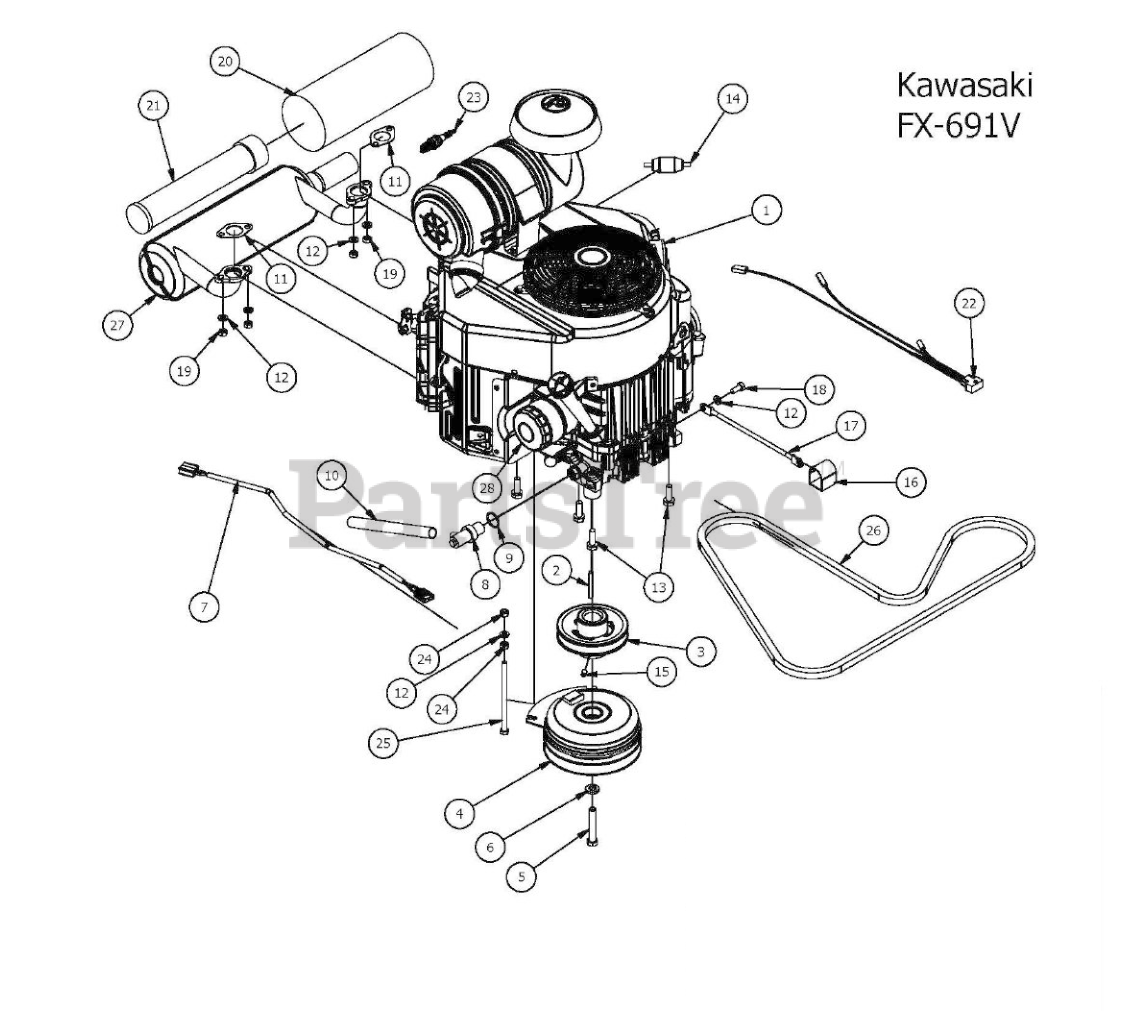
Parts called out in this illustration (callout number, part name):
2	1/4 x 2 Square key Stock
3	4 3/4 Motor Pulley
4	Clutch Assembly
5	7/16" x 2 1/2" Hex Bolt
6	7/16" Lock Washer
7	Clutch Pigtail
10	1/2 Clear Braded Hose Priced/Foot
11	Exhaust Gasket
12	5/16" Lock Washer
13	3/8 x 1 1/8 bolt
14	Universal Inline Fuel Filter
15	5/16 Set Screw
16	Black Boot For Ground Cable
17	Ground Cable
18	M8x1.20x20MM Hex head bolt
19	M8-1.25 Zinc Nut
20	Canister Air Filter- Outer
21	Canister Air Filter- Inner
22	Harness Adaptor
23	Spark Plug - Kawasaki
25	5/16-18 x 5-1/2 GR 5 Hex Bolt
27	Kawasaki Muffler 1251
28	Oil Filter
